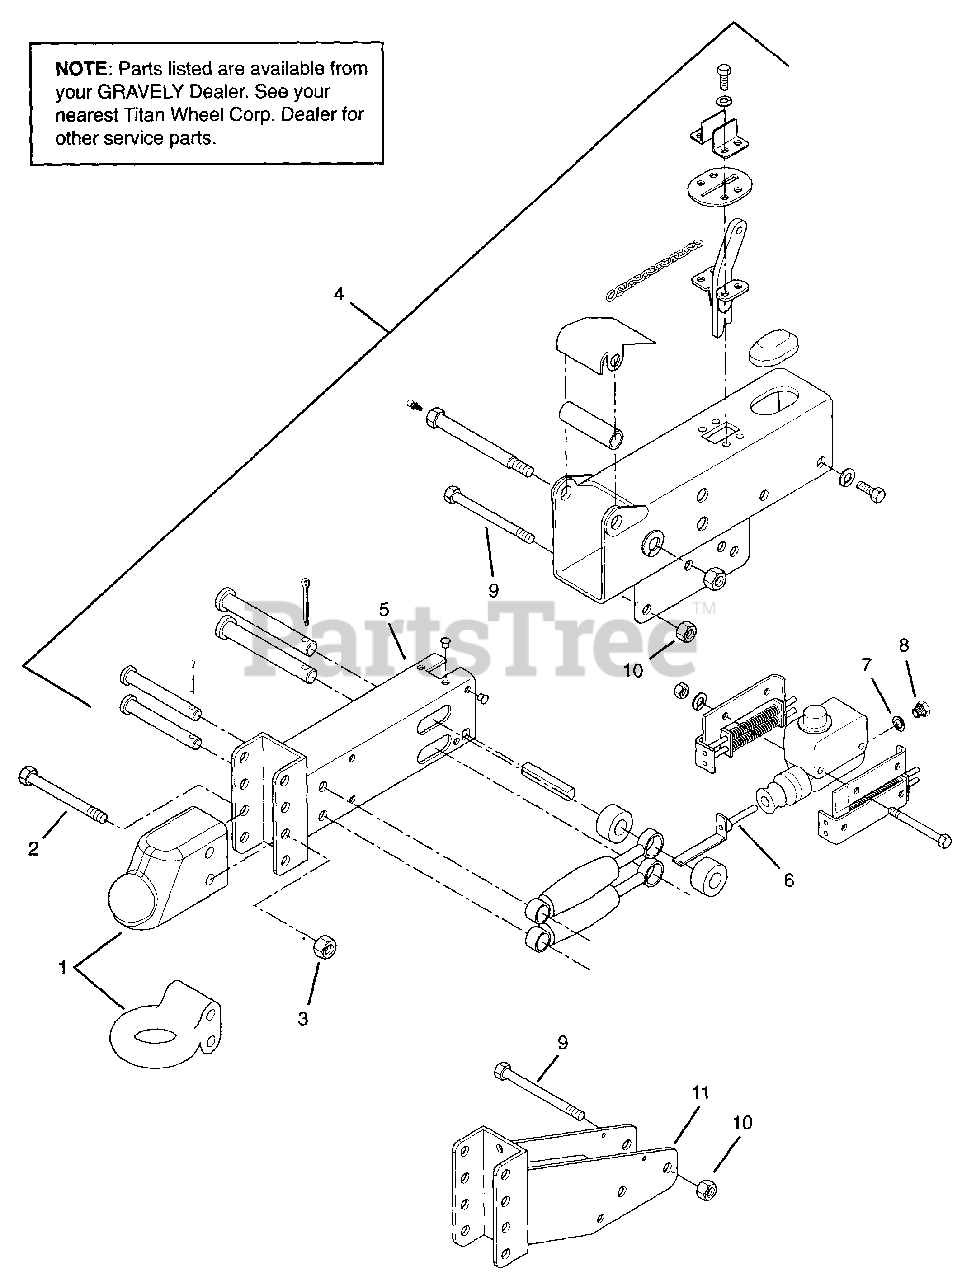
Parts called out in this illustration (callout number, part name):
1	Adjustable Ball Coupler
1	Hitch Ring
2	Bolt-Hex .62-11 x 4.25 Grade 5
3	Nut-Locking-Center .62-11
4	Actuator-Hydraulic Surge
5	Inner Slide Assembly with Channel
6	Push Rod Assembly
8	Connector
9	Bolt-Hex .50-13 x 4.00 Grade 5
10	Nut-Locking .50-13
11	Hitch Assembly
